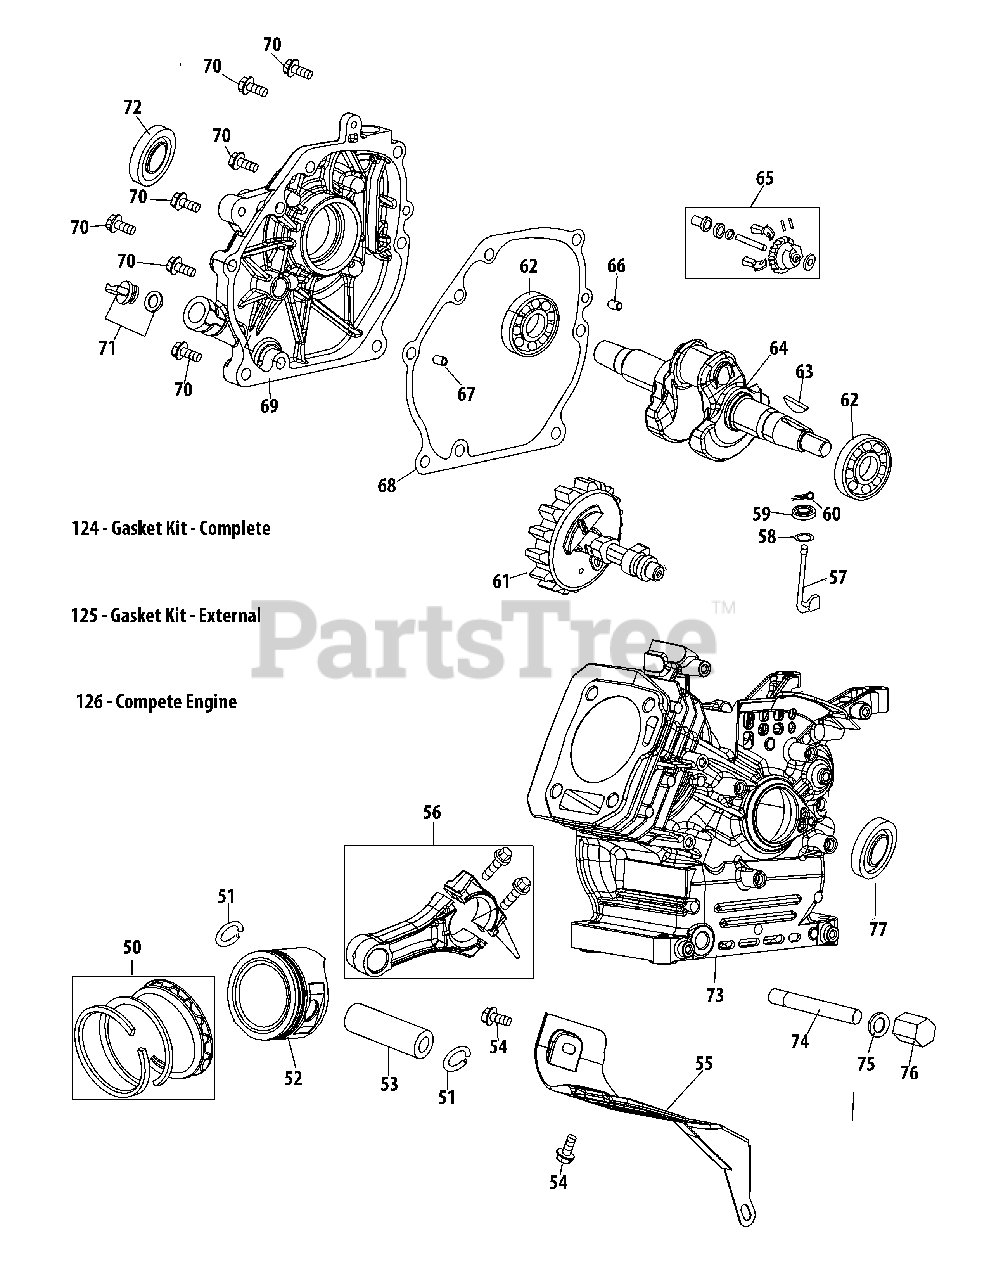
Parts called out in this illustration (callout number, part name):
50	Piston Ring Set
51	Piston Pin Snap Ring
52	Piston
53	Piston Pin
54	Bolt M6×12
55	Air Shield
56	Connecting Rod Assembly
57	Governor Arm Shaft
58	Washer - 5.2 X 1.9
59	Governor Seal
60	Cotter Pin
61	Camshaft Assembly
62	Bearing
63	Woodruff Key
64	Crankshaft Kit
65	Governor Gear Shaft Assembly
66	Dowel Pin 7×14
67	Dowel Pin 9×14
68	Crankcase Cover Gasket
69	Crankcase Cover
69	Crankcase Cover Kit
70	Bolt M8×32
71	Oil Fill Plug Assembly
71	O-Ring Only
72	Oil Seal
73	Crankcase Kit
73	Short Block Assembly
74	Extended Oil Drain Pipe
75	Drain Pipe Washer 10X16X1.5
76	Drain Plug Bolt
77	Oil Seal
124	Gasket Kit-Complete
125	Gasket Kit-External
126	Complete Engine
